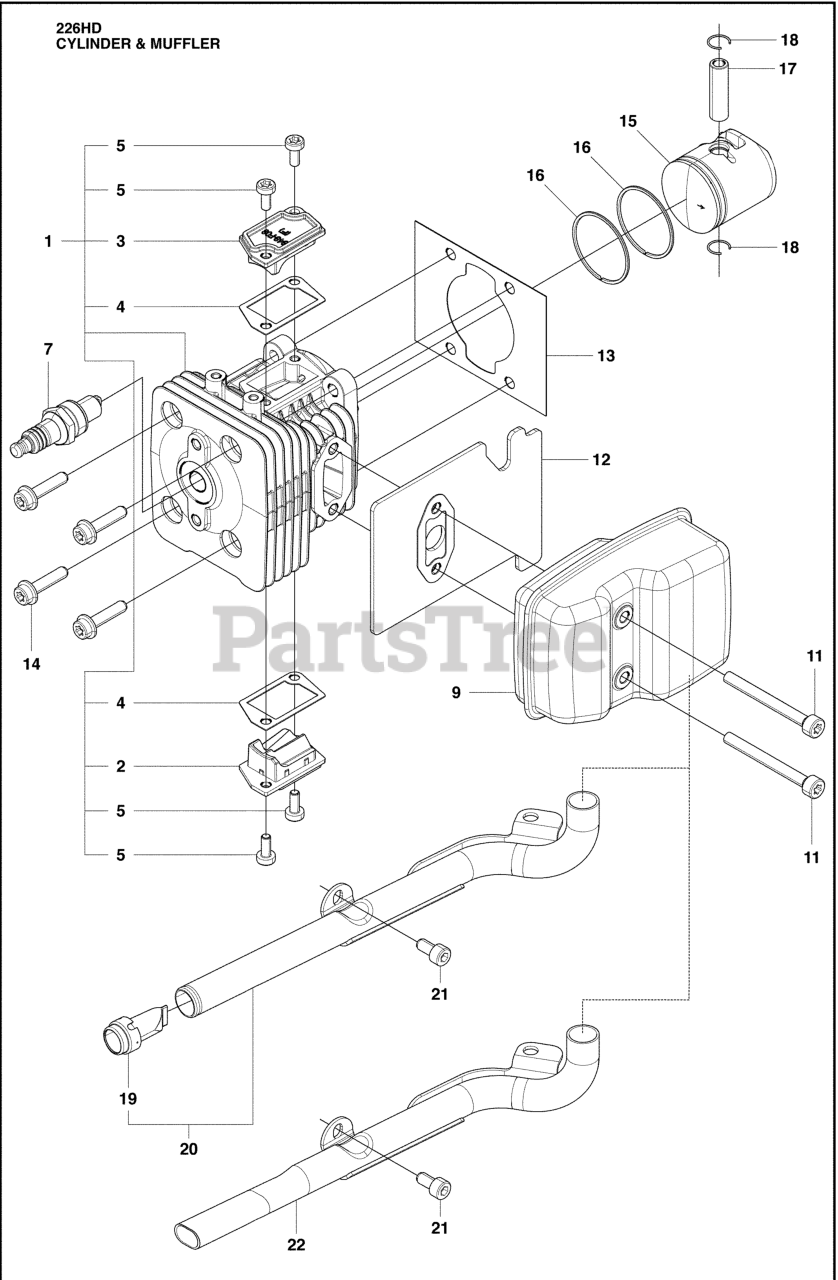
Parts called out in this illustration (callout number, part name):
1	CYLINDER COMPLETE
2	COVER, TR-S
3	COVER, TR-F
4	GASKET, TR
5	BOLT
7	SPARK PLUG NGK CMR7H
11	BOLT TORX M5XL50 T27
13	GASKET, BASE
14	BOLT TORX
20	EXHAUST PIPE
21	BOLT
